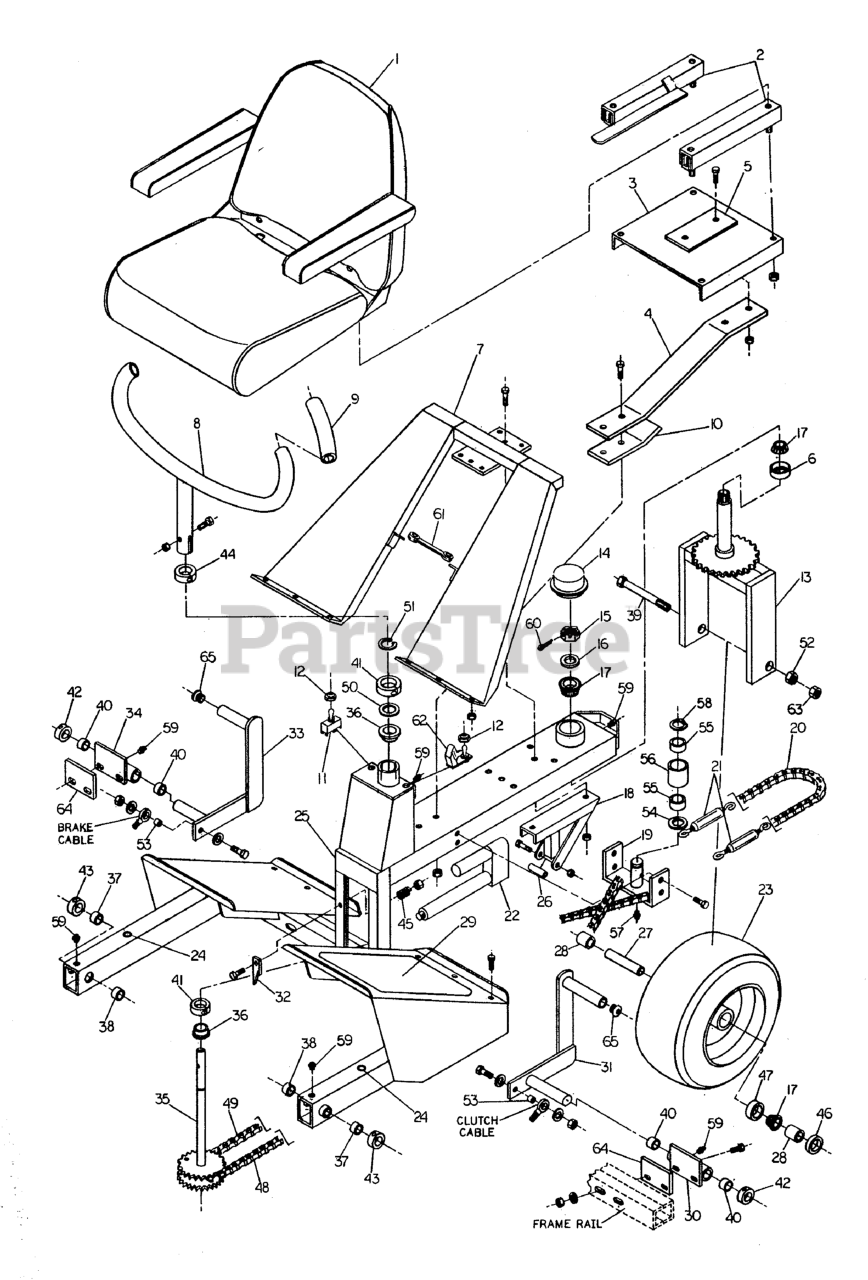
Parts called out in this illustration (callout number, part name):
1	CUSHION, BACK
1	CUSHION, BOTTOM
1	ARM REST, RH
1	ARM REST, LH
2	SEAT ADJUSTER RAILS (set of 2)
3	PLATE, Seat
4	SEAT SPRING
5	SUPPORT, Seat Plate
6	SEAL, GREASE
7	Rider Frame Support
8	STEERING HANDLE
9	GRIP, Foam
10	SUPPORT, Seat Spring
11	Toggle Switch
12	Toggle Boot
13	MOUNT, Steering Tire
14	CAP
15	NUT, 3/4-16 Hex Slotted
16	WASHER, 3/4 SAE
17	BEARING, Tapered Roller
18	Actuator Mount
19	Chain Roller Mount
20	CHAIN, #40 Roller, 36 Links
21	TURNBUCKLE
22	Electric Actuator
23	WHEEL & TIRE ASSEMBLY, 18 x 7.5 x 8, White, Complete
24	GROMMET, 1/2"
25	Rider Frame Weldment
26	Actuator Spacer
27	STEERING TIRE AXLE
28	SPACER, 1.01 X 1.25 X 2.06
29	SAFETY WALK
30	Clutch Pedal Bracket Weldment
31	Clutch Pedal Weldment
32	Brake Lever
33	Brake Pedal Weldment
34	Brake Pedal Bracket
35	SHAFT, Steering Sprocket
36	BUSHING, Flange
37	BUSHING, Brass
38	BUSHING
39	BOLT, 5/8-11 x 9-1/2
40	BUSHING, Brass
41	COLLAR, 1-1/4" Split
42	COLLAR, 3/4" Set
43	COLLAR, 3/4" Split
44	COLLAR, 1" Split
45	SPRING, Compression
46	GREASE SEAL
47	BEARING CUP
48	CHAIN, #40 Roller, 31 Links
49	CHAIN, #40 Roller, 31 Links
50	SHIM
51	Snap Ring
52	NUT, 5/8-11 Hex
53	SPACER, .26 X .38 X .50
55	Bushing
56	CHAIN ROLLER
57	45 Degree Grease Fitting
58	SNAP RING, External
59	GREASE FITTING
60	PIN, COTTER, 1/8 X 1-1/4
61	RUBBER STRAP
62	Toggle Switch
62	Switch Guard
63	NUT, 5/8-11 Hex Side Lock
64	Foot Pedal Bracket
65	End Plug
